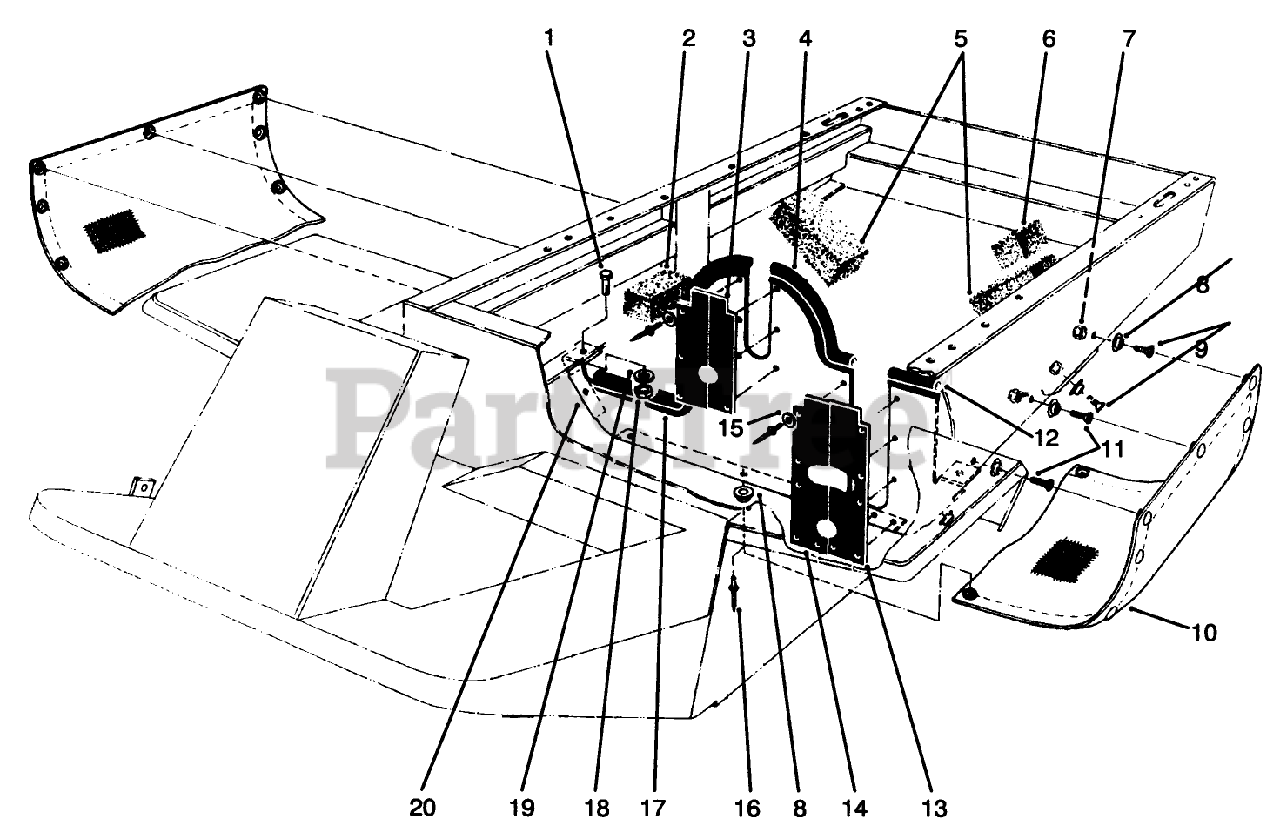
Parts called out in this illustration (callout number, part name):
1	SCREW-HH
2	SIDE FOAM
4	TRIM SEAL
5	REAR FOAM
6	LH REAR FOAM
7	NUT-HEX
8	SNAP STUD
9	6-32 X 5/8 FLAT HD SCR
10	GRASS SCREEN BAG
11	SCREW-HWH
12	TRIM SEAL
13	LH FLAP
14	RH FLAP
15	WASHER
16	RIVET-POP
17	TRIM SEAL
18	NUT-HEX
19	WASHER-LOCK/SP
20	Front Shield Assembly (Incl. Ref. #3, 4, 8 &12-17)
